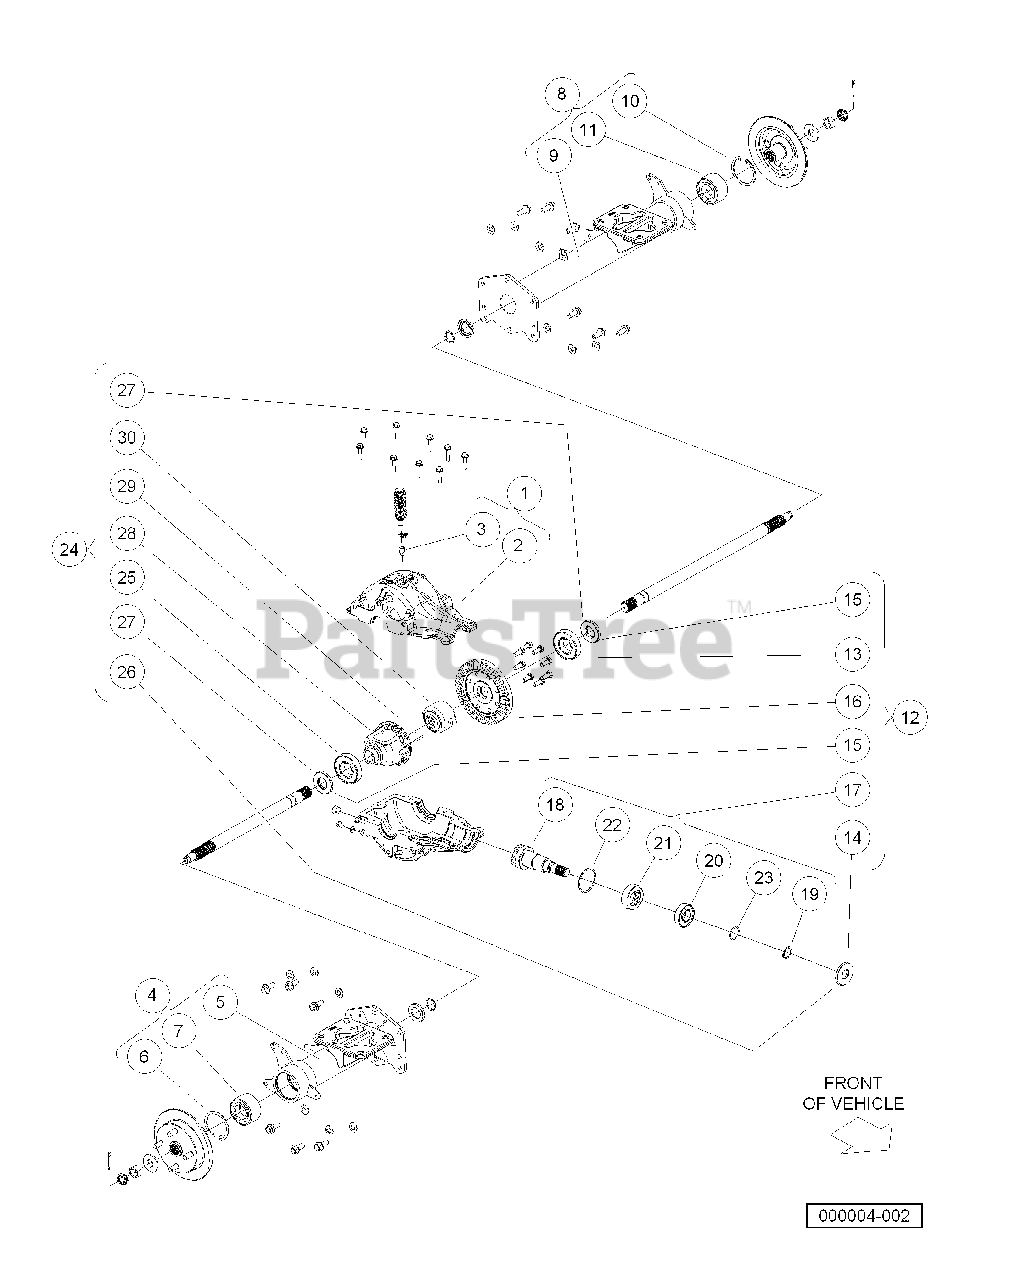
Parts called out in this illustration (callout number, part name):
1	Asm, Gearcase, Upper
2	Gearcase, Upper, Machined
3	Vent, Top, Upper Housing
4	Asm, Axle Tube, RH
5	Weldment, Axle Tube Rh
6	Ring, Retaining, Internal
8	Asm, Axle Tube, LH
9	Weldment, Axle Tube Lh
10	Ring, Retaining, Internal
12	Kit, Rear Axle Gear Repair
13	Bearing, Ball
14	Seal, Dual-Lip 25x 62x 7tc
15	Seal, Dual-Lip 30x 62x 8tc
17	Asm, Pinion W/ Bearings
18	Pinion, I0t Machined
19	Ring, Retaining, External
20	Bearing, Ball
21	Bearing, Needle, Drawn Shell
22	Washer, 2.625 X 2.367 X .06
23	Shim, 1.50 X 1.189 X .008
24	Asm, Differential & Carrier
25	Bearing, Ball
26	Seal, Dual-Lip 25x 62x 7tc
27	Seal, Dual-Lip 30x 62x 8tc
28	Housing, Differential, Mach
29	Pin, Dowel, 4 X 35
30	Asm, Locker, Nongrease/Spacers
